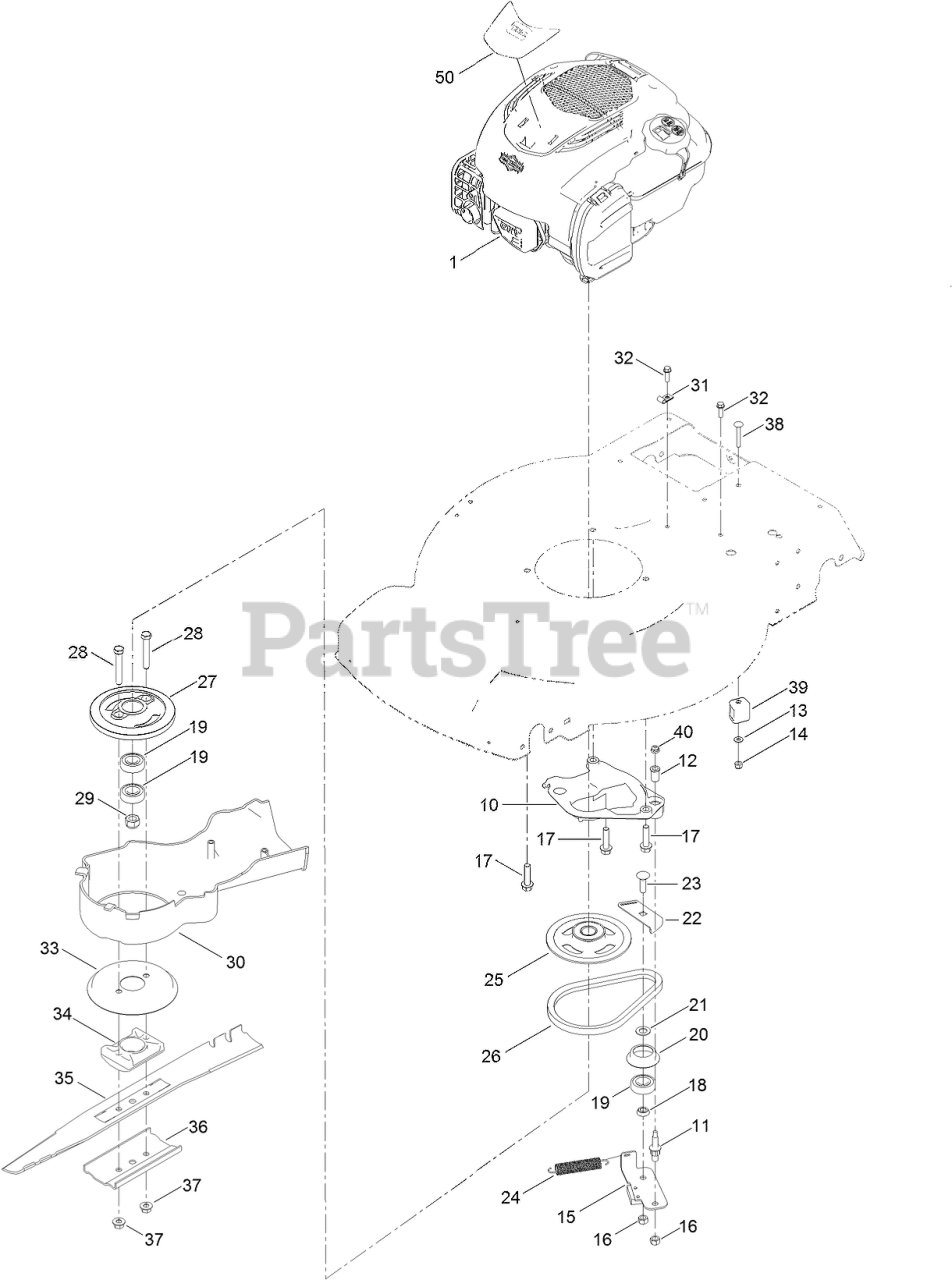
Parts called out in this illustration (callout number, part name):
1	ENGINE-BRIGGS 675 EXI BBC EU
10	PLATE-ANCHOR
11	BOLT-SHOULDER
12	BUSHING
13	WASHER-FLAT
14	NUT-LOCK, NI
15	PLATE-BRAKE
16	LOCKNUT
17	SCREW-HWH
18	SPACER-BEARING
19	BEARING-BALL
20	RETAINER-BELT
21	SPACER
22	PLATE-GUIDE
23	SCREW-CARR
24	SPRING-TENSION, BRAKE
25	PULLEY
26	BELT
28	SCREW-HH
29	NUT-HEX
31	CLIP-CLOSED, INSULATED
32	SCREW-HWH
34	SUPPORT-BLADE
36	SUPPORT-BLADE
37	NUT-FLANGE, LOCK
38	SCREW-CARR
39	ANCHOR-CABLE
40	NUT-HF
50	DECAL-SHROUD
